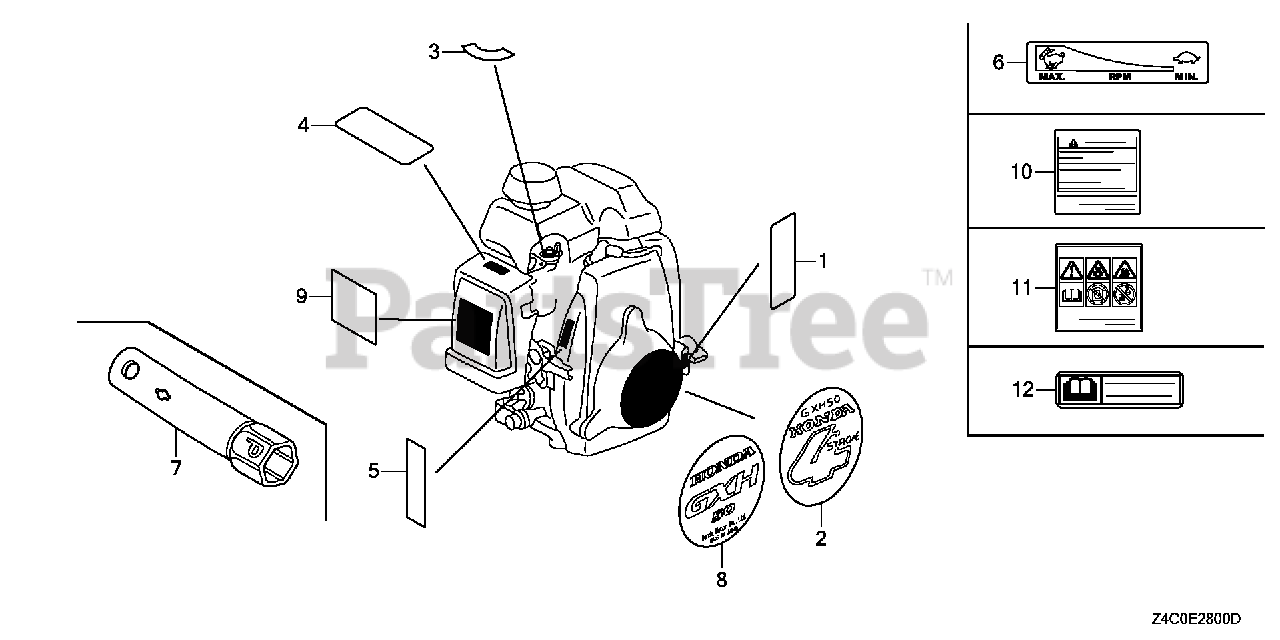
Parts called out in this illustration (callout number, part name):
2	EMBLEM (4STROKE)
2	EMBLEM (GXH50)
3	MARK, PETCOCK (EXTERNAL)
5	MARK, THROTTLE INDICATION
7	WRENCH, SPARK PLUG
8	EMBLEM (GXH50)
9	MARK, OPERATOR CAUTION (ENGLISH)
10	MARK, OPERATOR CAUTION (FRENCH)
11	MARK, OPERATOR CAUTION (PICTOGRAPH)
